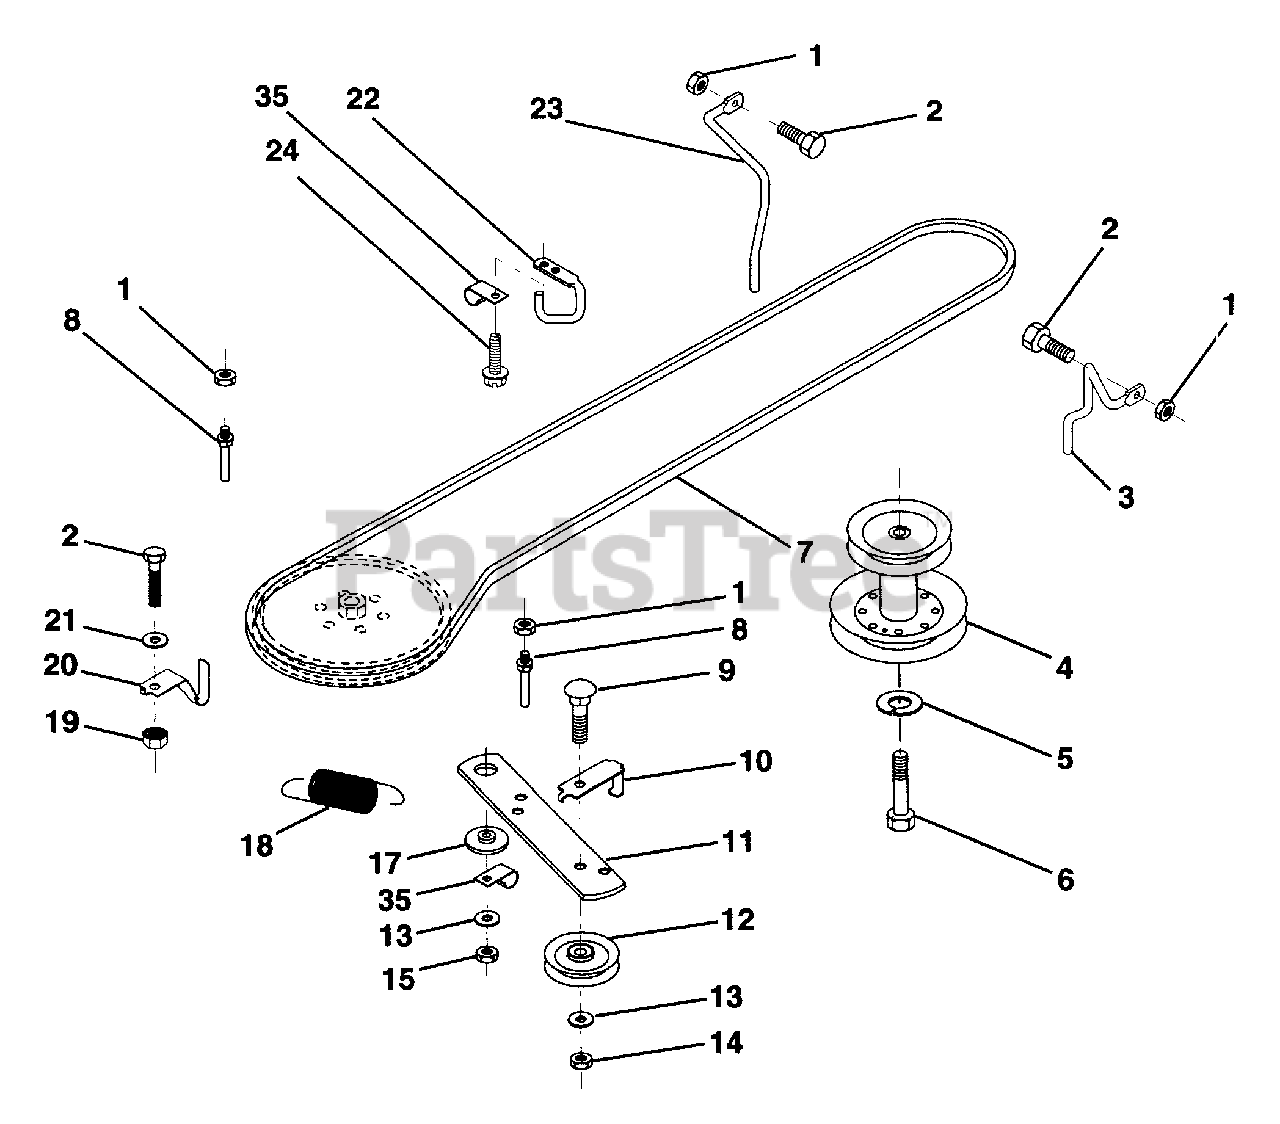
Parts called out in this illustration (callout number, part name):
1	Nut, Crownlock 5/16-18
2	Bolt, Hex Head 5/16-18 UNC x 3/4
3	Keeper, Mower Drive, R.H.
4	Pulley, Engine
5	Washer, Lock 7/16
6	Bolt, Hex Hd. 7/16-20 UNF Grade 5
7	Traction, V-Belt Drive
8	Keeper, T/A, Ground Drive Belt
9	Bolt, Carriage 3/8-16 UNC x 1-1/2
10	Keeper, Ground Drive Belt Idler
11	Arm, Ground Drive Clutch
12	Idler, Flat
13	Washer 13/32 x 13/16 x 16 Gauge
14	Nut, Hex, Centerlock 3/8-16 UNC
15	Nut, Hex, Crownlock 3/8-16 UNC
17	Spacer, Retainer
18	Spring, Extension
19	Nut, Hex, Keps 5/16-18 UNC
20	Keeper, T/A, Ground Drive Belt
21	Washer 11/32 x 5/8 x 16 Gauge
22	Keeper, Frame Ground Drive Belt
23	Keeper, Belt LH
24	Screw, THD Cut
35	Clip Insulated
